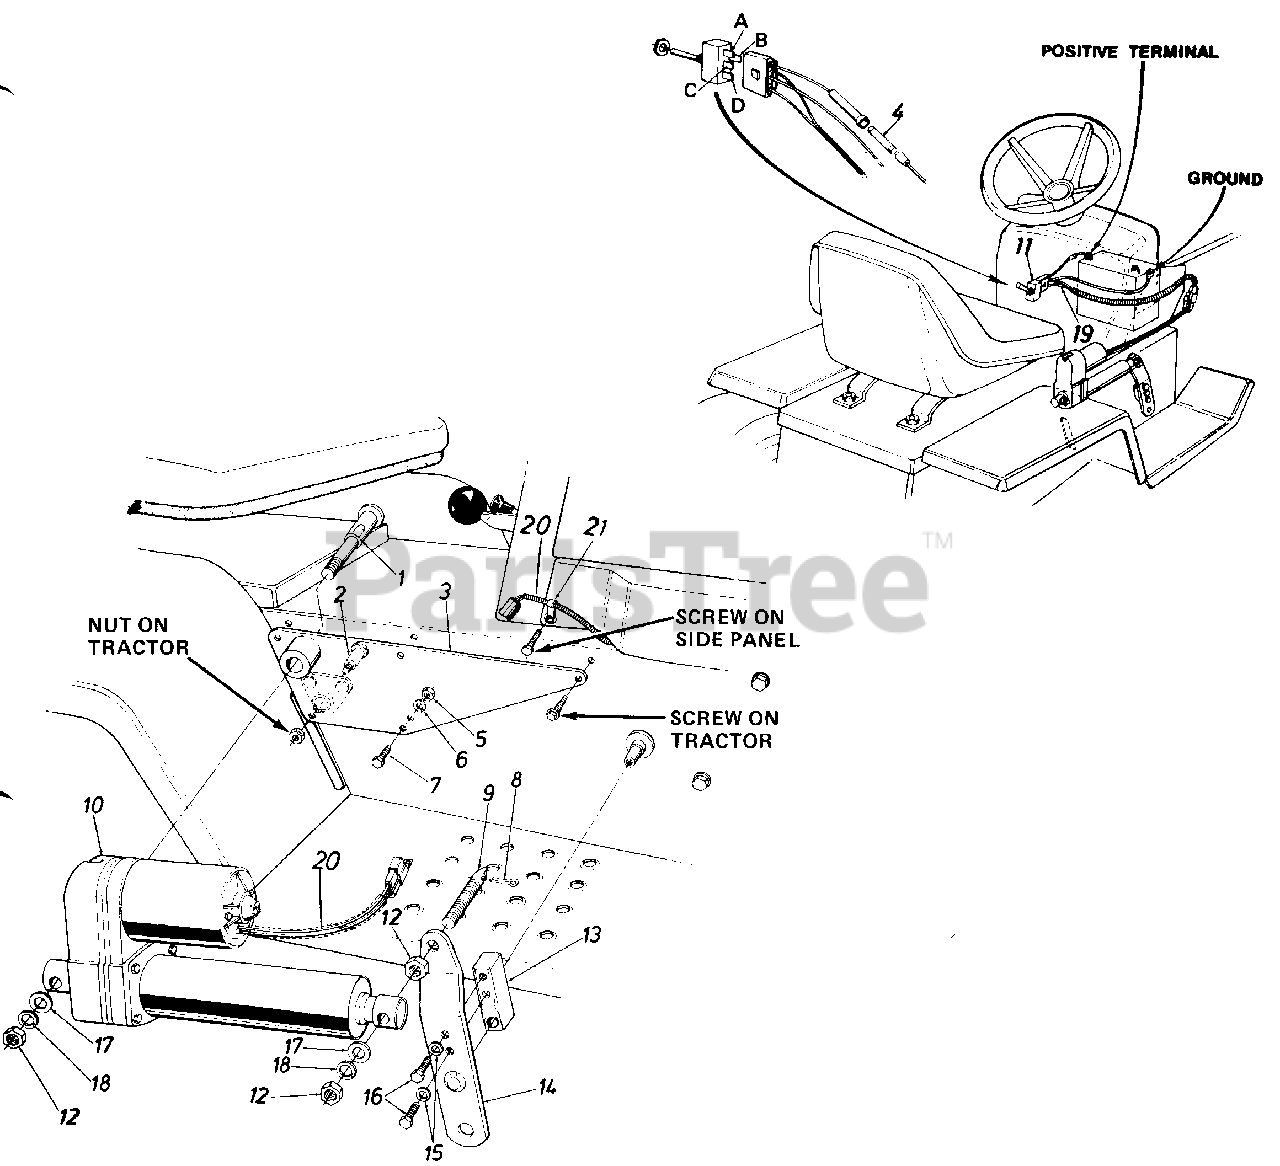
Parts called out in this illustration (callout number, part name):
1	Pivot Pin
2	Shld. Bolt .626 Dia. x .96"
5	Hex Nut 1/4-28 Thd.
6	L-Wash. 1/4" I.D.*
7	Hex Bolt 1/4-28 x .75" Lg. (Grade 5)
8	Cotter Pin
9	Indicator & Mtg. Pin
10	Electric Actuator
11	Toggle Switch
12	Hex Jam Nut 1/2-13 Thd.
13	Lift Shaft Drive
16	Hex Bolt 5/16-24 x 1.0" Lg. (Grade 5)
17	Fl-Wash. .53" I.D. x.93" O..
18	L-Wash. 1/2" I.D.*
19	Wire Harness
20	Plastic Tubing-7"
21	Clamp
